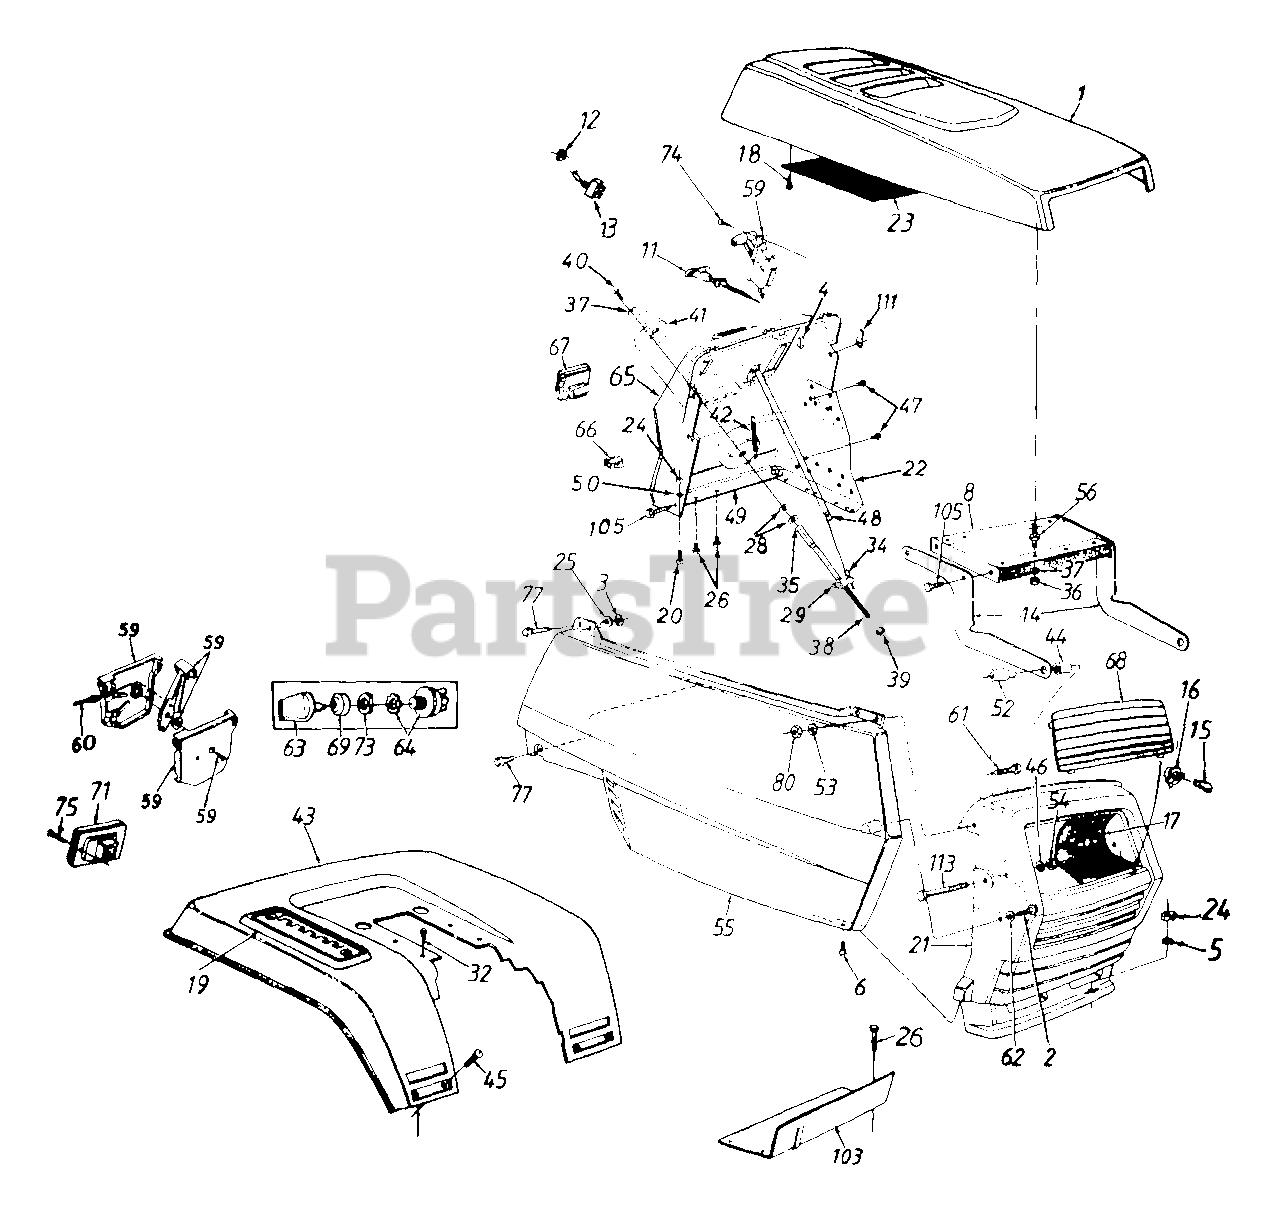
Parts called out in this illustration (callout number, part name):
1	Hood
2	Hex Wash. B-Tap Scr. 1/4 x .62" Lg.
3	Bolt Retainer 1/4" I.D.
4	Retainer Clip
5	Fl-Wash. .34" 1.0. x 1"
6	Truss Mach. B-Tap Scr. #10 x .5" Lg.
12	Hex Nut 1/2-27 Thd.
13	Toggle Switch
16	Twist Lock - Lamp Socket
17	Reflector - Headlight
18	Hex Wash. Hd. AB-Tap Scr. #8 x .5" Lg.
21	Grille
24	Hex Nut 5/16-18 Thd.
25	Fl-Wash. 1/4" I.D. x .93" O.D.
26	Hex Wash. Hd. B-Tap Scr. 5/16-18 x .5" Lg.
28	Fl-Wash. 3/8" I.D. x .875" O.D.
29	Adj. Ferrule 3/8-8 Thd.
34	Hairpin Clip
35	"E"-Ring .375" Dia.
36	Hex Nut 1/4-20 Thd.
37	Bell-Wash. .265" I.D. x .75"
38	Adjustment Rod
39	Hex Nut 3/8-8 Twin Thd.
40	Hex Bolt 1/4-20 x .75" Lg.
41	Plastic Knob
42	Ext. Spring 3.21" Lg.
45	Carriage Bolt 1/4-20 x .50" Lg.
46	Fl-Wash. .328" I.D. x .68" O.D.
47	Hex Wash. Hd. Scr. 1/4-20 x .5" Lg.
48	Indicator Strip
52	Shld. Spacer .33" I.D.
53	Fl-Wash. .281" I.D. x .5" O.D.
54	Hex Cent. L-Nut 5/16-18 Thd.
55	Side Cover - R.H.
56	Double Ended Stud 1/4-20 Thd.
59	Throttle Control Box Ass'y.
60	Throttle Control Wire 22" Lg.
61	Hex Bolt 1/4-20 x .62" Lg.
62	Fl-Wash. .281" I.D. x .73" O.D.
64	Ignition Switch
65	Dash Panel
66	Light Switch
67	Ammeter
68	Lens
69	Ignition Switch Cap
71	Tail light
73	Ignition Switch Nut
74	Truss Mach. AB-Tap Scr. #10 x .5" Lg.
75	Truss Hd. AB-Tap Scr. #6 x .62" Lg.
77	Hex Wash. Hd. Tap Scr. 1/4 x .75" Lg.
80	Hex L-Nut 1/4-20 Thd.
111	Speed Nut 1/4-20 Thd.
113	Hex Bolt 5/16-18 x 2.75"
